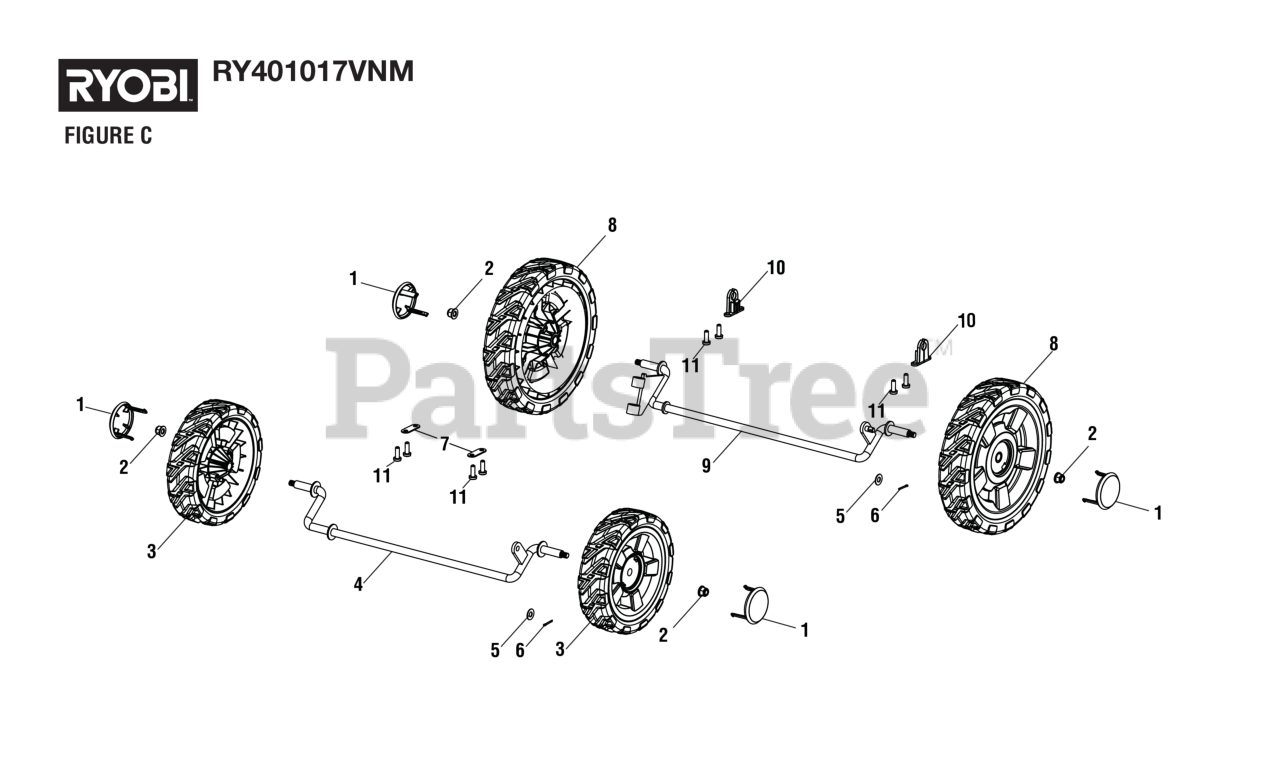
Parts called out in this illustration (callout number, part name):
1	Wheel Hub Cap
2	Flange Lock Nut (M8 x 1.25 mm)
3	8 in. Wheel
4	Front Wheel Axle
5	Washer (ID8.4 x OD18 x 1t)
6	Cotter PinÏ? (2.5)
7	Front Axle Press Plate
8	10 in. Wheel w/Bushing Assembly
9	Rear Wheel Axle
10	Rear Axle Mount Plate Bushing
11	Screw (1/4-15 x 3/4 in., T30 Torx Pan Hd.)
